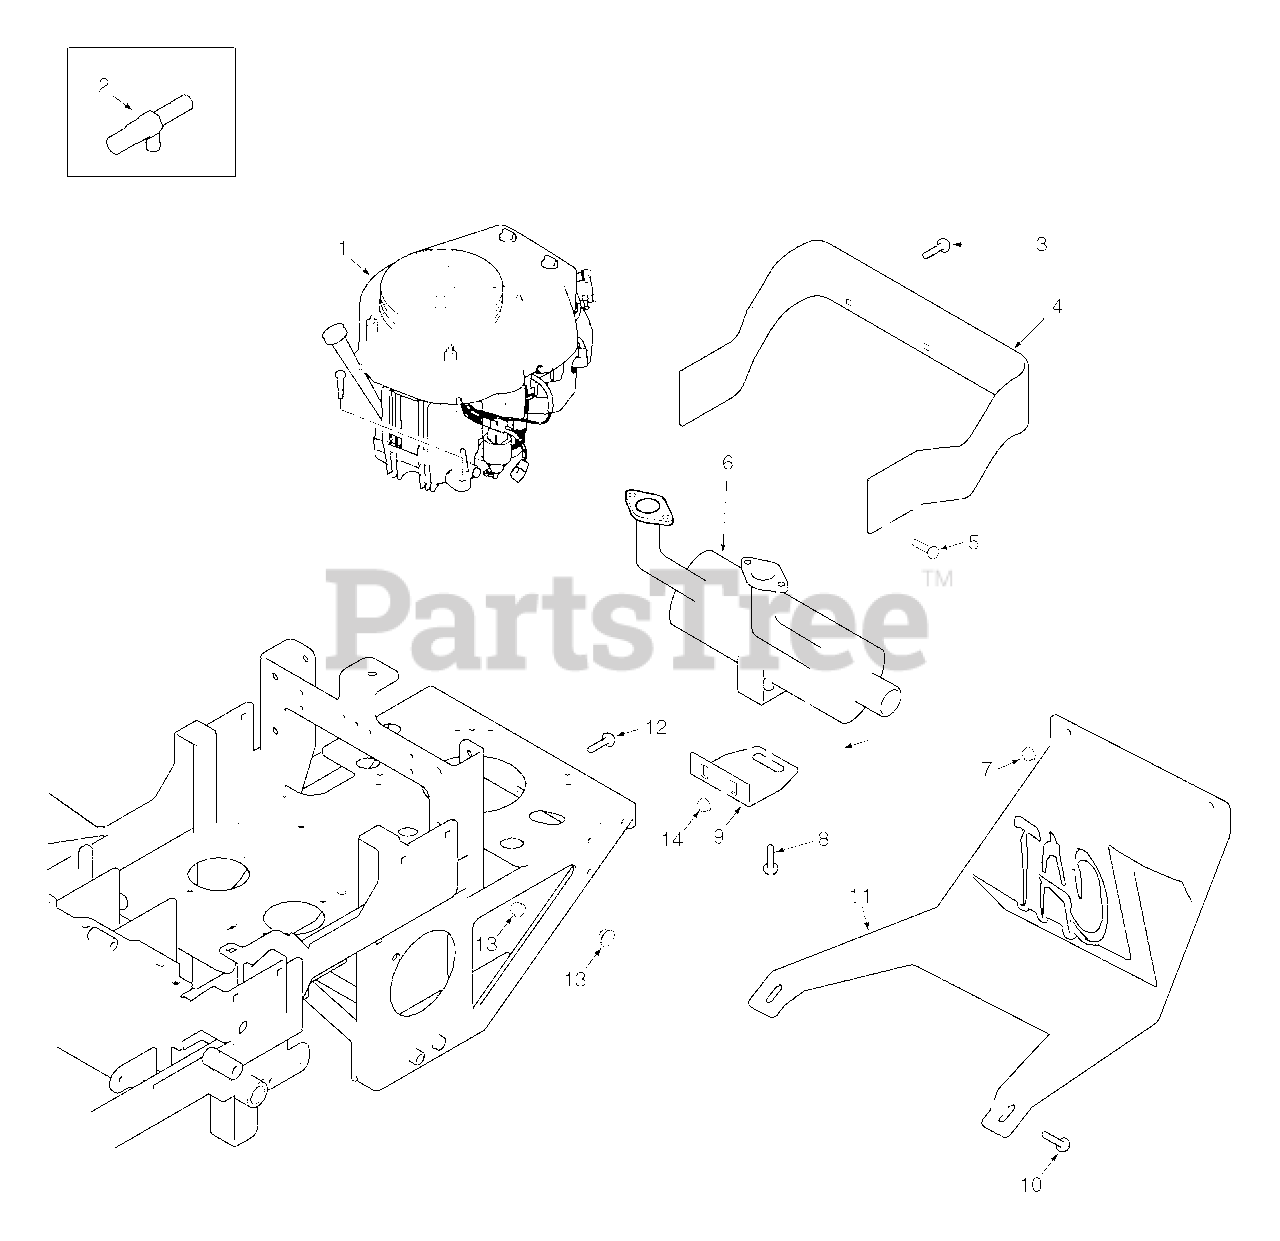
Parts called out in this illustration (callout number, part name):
1	Engine, Honda 16hp
2	Extension, Oil Drain 4"
3	Bolt, Torx 3/8-16 x 1"
4	Bumper, Rear
5	Bolt, Hex Head 3/8-16 x 1"
6	Muffler, SZC Kawasaki
7	Nut, Serr. Flange 3/8-16
8	Bolt, 5/16-18 x 3/4" Self Tap
9	Mounting Bracket, Muffler
10	Bolt, Torx 3/8-16 x 1"
11	Skidplate
12	Bolt, Carriage 5/16-18 x 3/4"
13	Nut, Elastic Stop 3/8-16
14	Nut, Elastic Stop 5/16-18
15	Bolt, Carriage 5/16-18 x 3/4"
